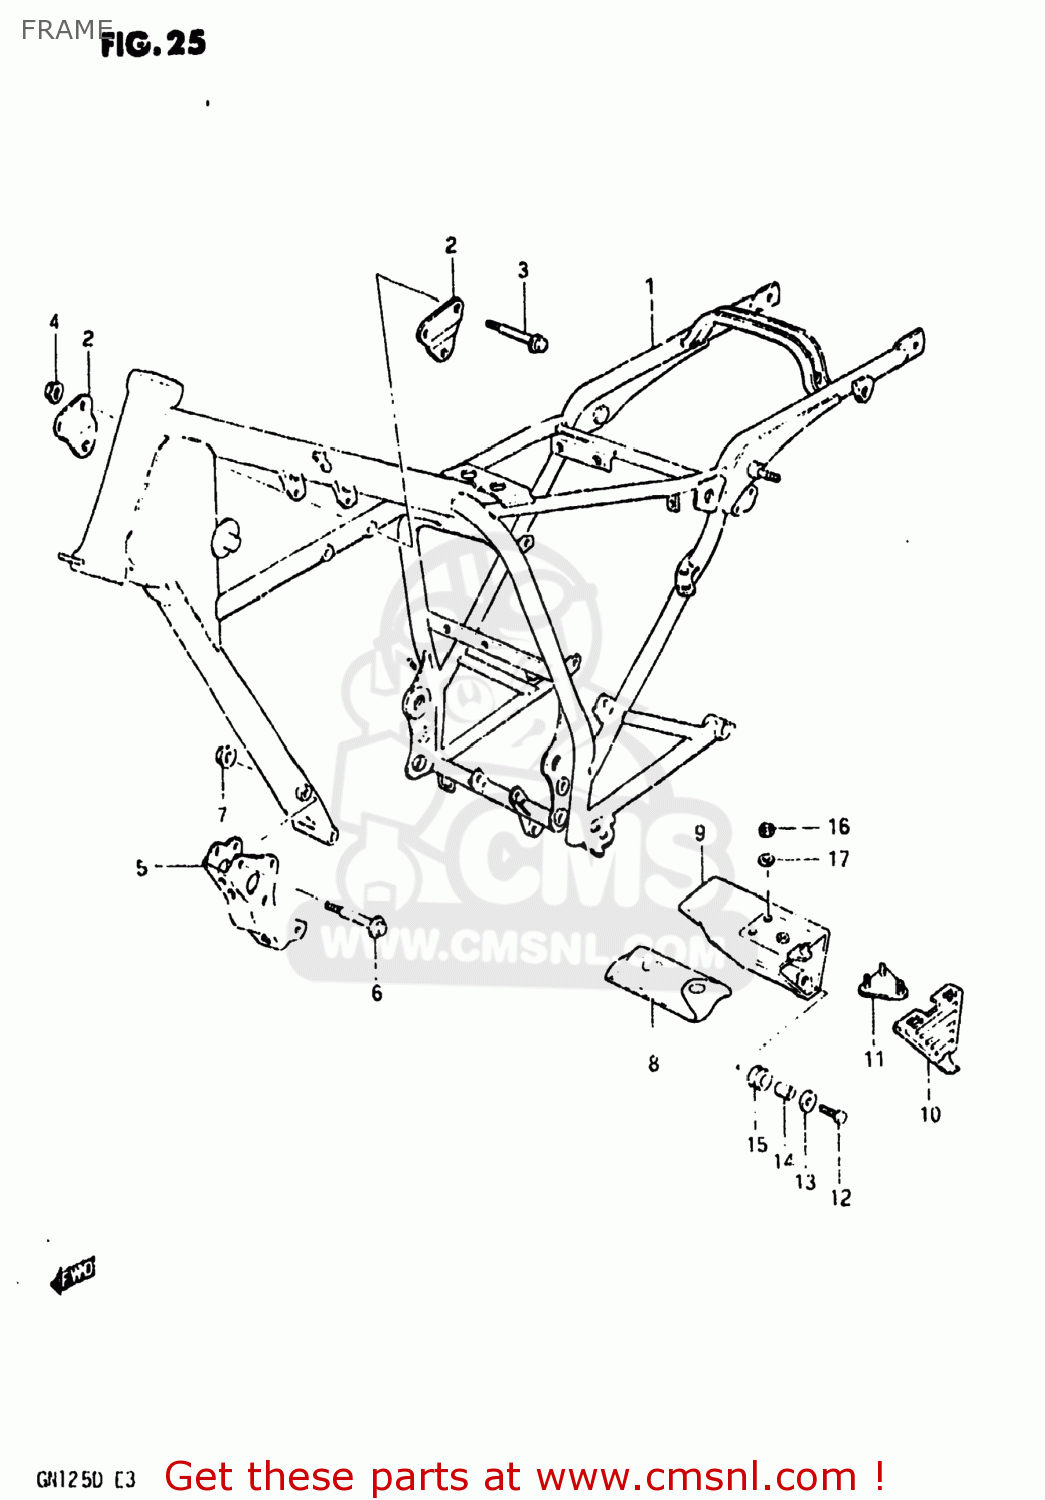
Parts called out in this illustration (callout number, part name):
1	FRAME
2	PLATE,ENGINE MOUNTING
3	BOLT
4	NUT
5	BRACKET,ENGINE MOUNTING LWR
6	BOLT
7	NUT
8	TOOL SET
9	BOX,TOOL
10	CAP,TOOL BOX
11	PLATE,TOOL HOLDER
12	BOLT, UPPER
13	WASHER (6.5X20X1.2)
14	SPACER(6.1X9X7.5)
15	CUSHION
16	NUT
17	WASHER
